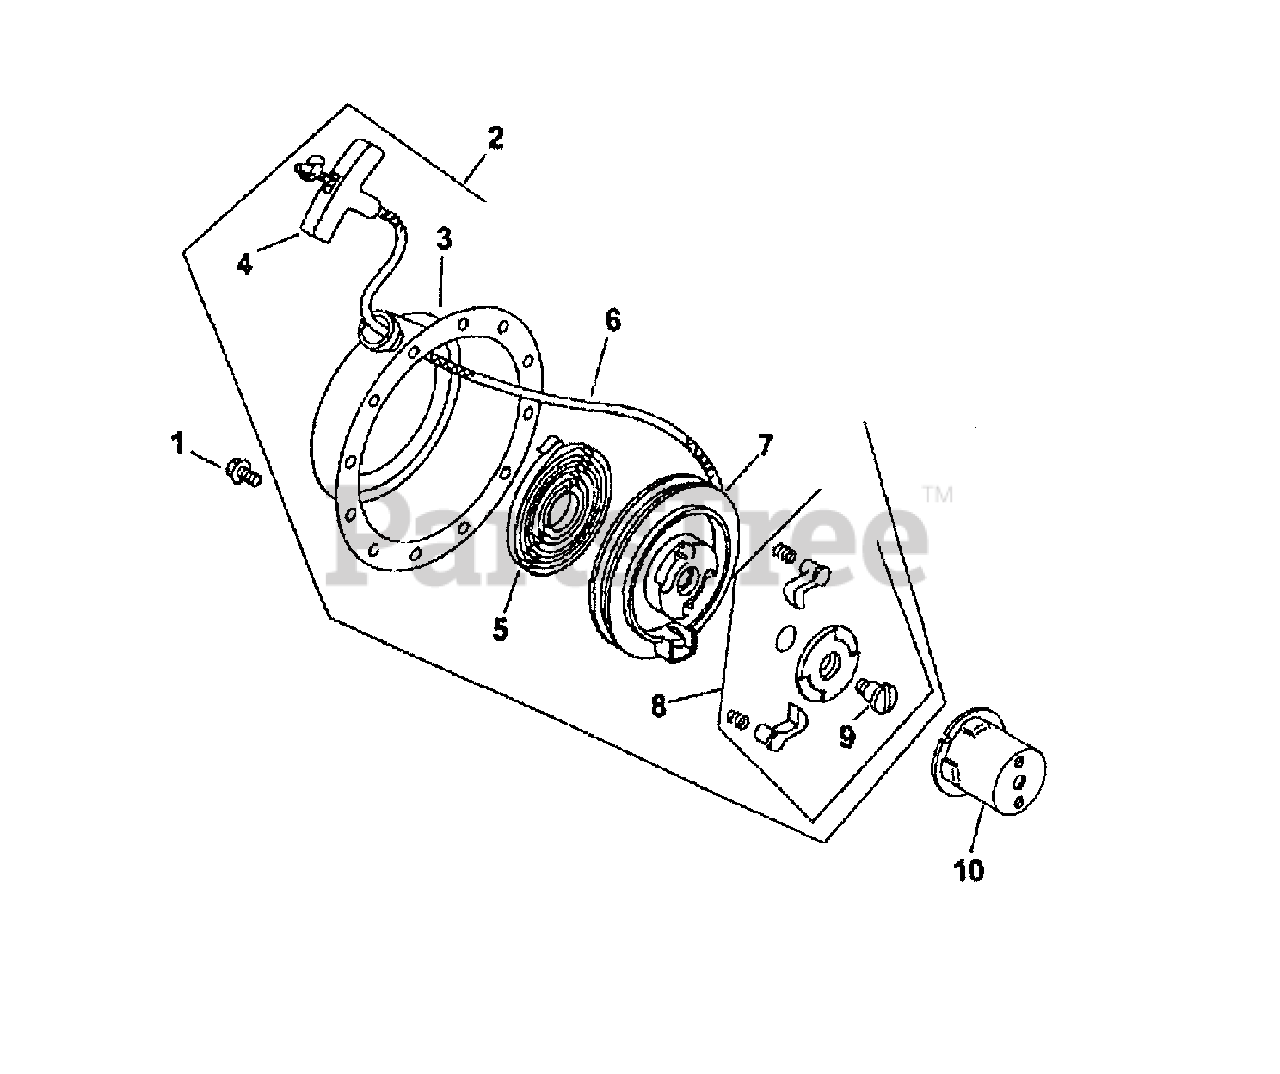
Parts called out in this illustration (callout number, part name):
2	Starter, Retractable
3	Housing Assembly
4	Handle, Starter
5	Spring, Recoil
6	Rope, Starter
8	Kit, Pawl Repair
10	Cup, Starter Drive
